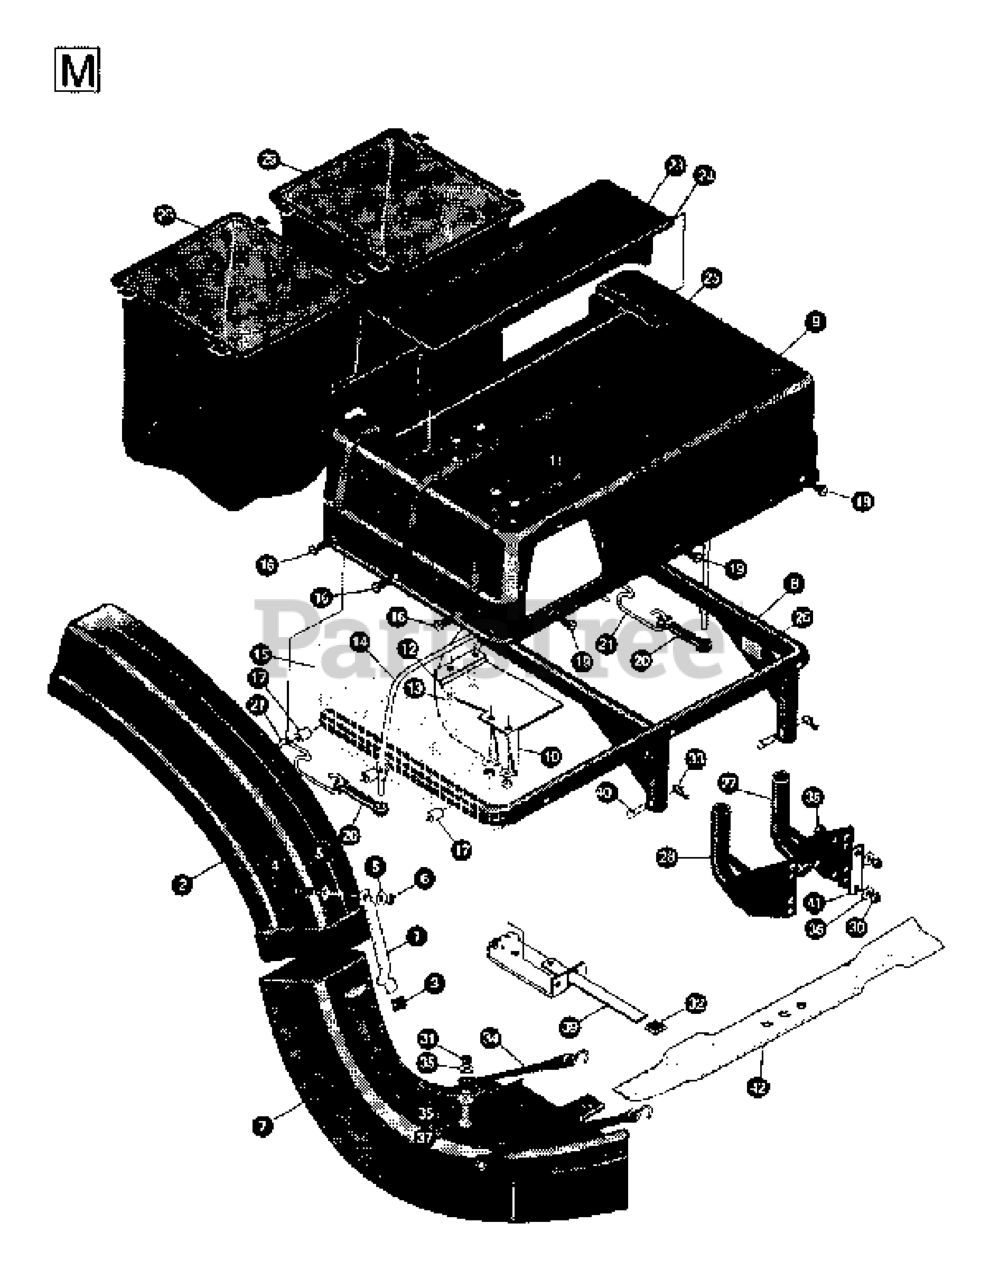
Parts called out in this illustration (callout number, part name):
3	TAB
4	SCREW
5	WASHER - M6
6	NUT
10	BAFFLE NLA
11	SCREW
12	WASHER
13	NUT
16	SCREW
19	SCREW
30	NUT
31	NUT
32	TAB
35	WASHER
36	WASHER
37	SCREW
38	BOLT.FIN.HEX.5/16-18UNC X 1.00
42	CUTTING BLADE
